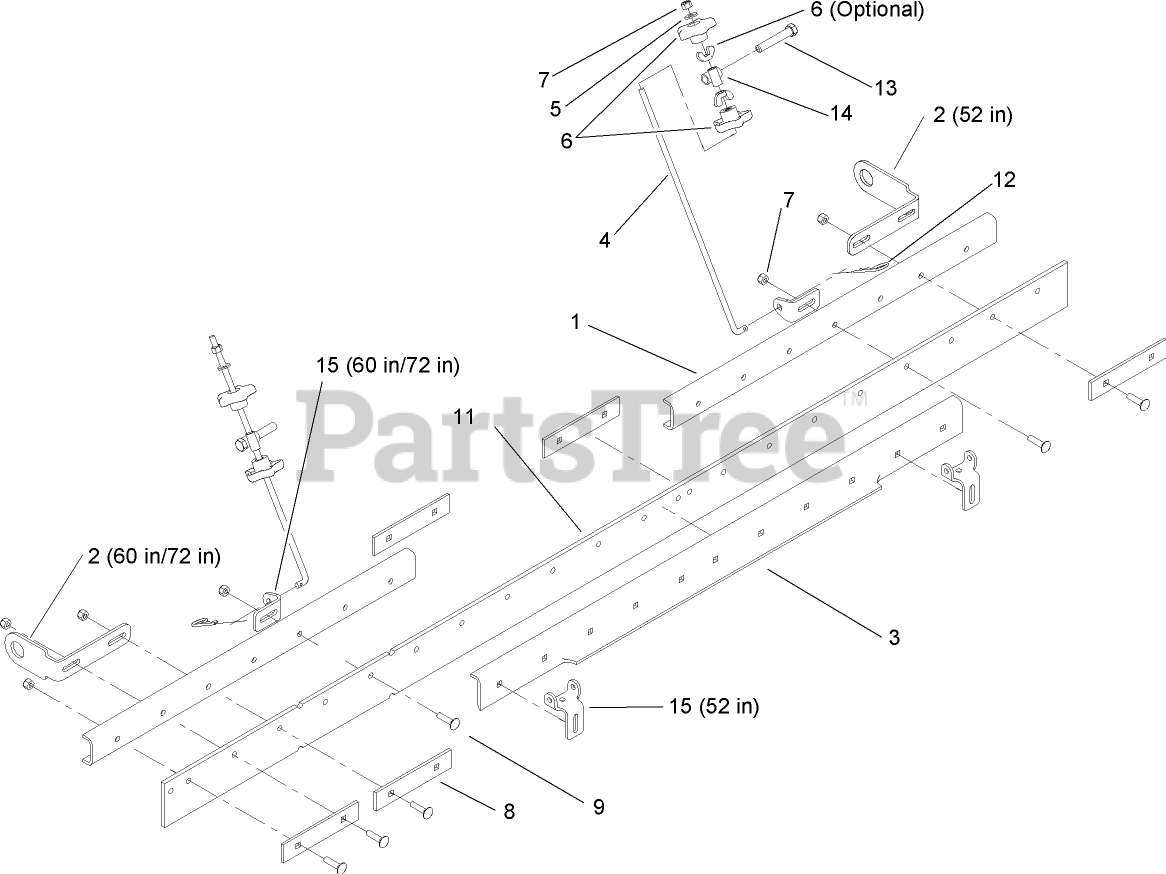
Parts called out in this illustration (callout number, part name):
1	BAR-STRIPING
2	MOUNT-PIVOT, 52IN
2	MOUNT-PIVOT, 60IN/72IN
3	BAR-SUPPORT
4	ROD-LIFT
5	WASHER-FLAT
6	KNOB-HANDLE
6	NUT-WING
7	NUT-LOCK, NI
8	SUPPORT-STRIPER
9	SCREW-CARR
11	WIPER-STRIPING
12	PIN-COTTER
13	SCREW-HH
14	MOUNT-ADJUSTER
15	BRACKET-ADJUSTER, 60IN/72IN
15	BRACKET-ADJUSTER, 52IN
